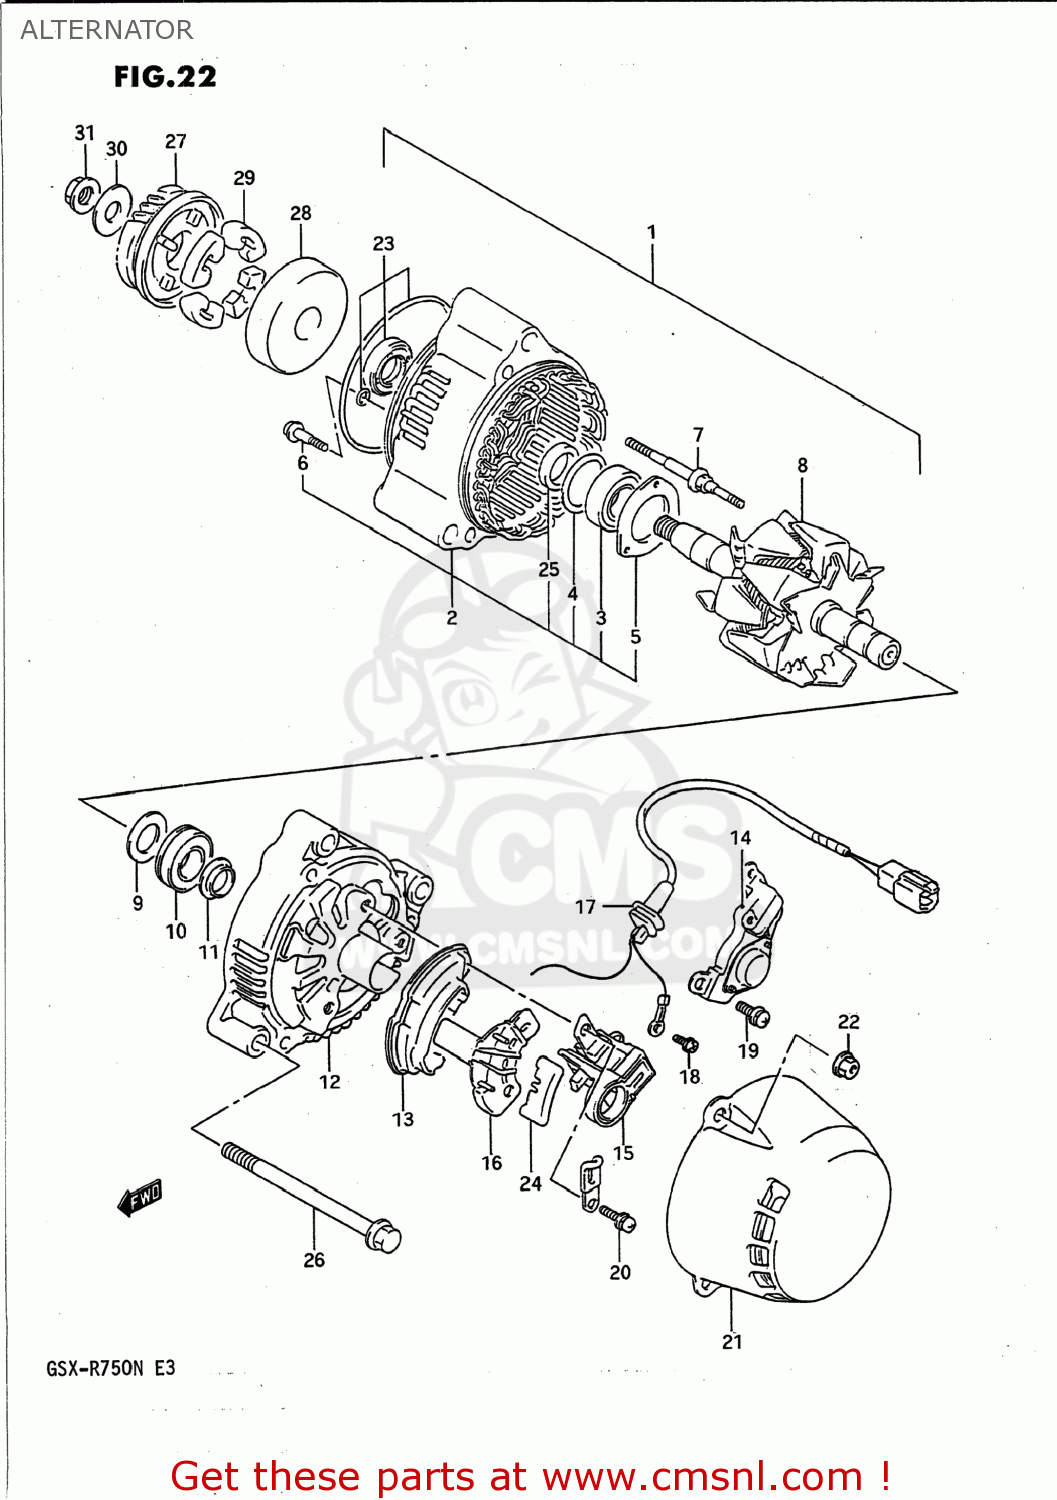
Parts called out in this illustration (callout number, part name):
1	GENERATOR ASSEMBLY
2	FRAME,DRIVE END
3	BEARING
4	COVER,BEARING
5	RETAINER
6	SCREW,BEARING RETAINER
7	STUD BOLT
8	ROTOR ASSEMBLY
9	COVER,BEARING
10	BEARING
11	COVER(2)
12	FRAME,END
13	HOLDER,RECTIFIER
14	REGULATOR
15	HOLDER,BRUSH
16	COVER,RECTIFIER
17	WIRE,LEAD
18	SCREW
19	SCREW
20	SCREW
21	COVER
22	NUT ,5MM
23	SEAL SET,OIL
24	BUSH
25	SPACER
26	BOLT 8X90
27	GEAR,GENERATOR DRIVEN
28	HOUSING,GENERATOR GEAR
29	DAMPER,GENERATOR DRIVEN
30	WASHER
31	NUT
